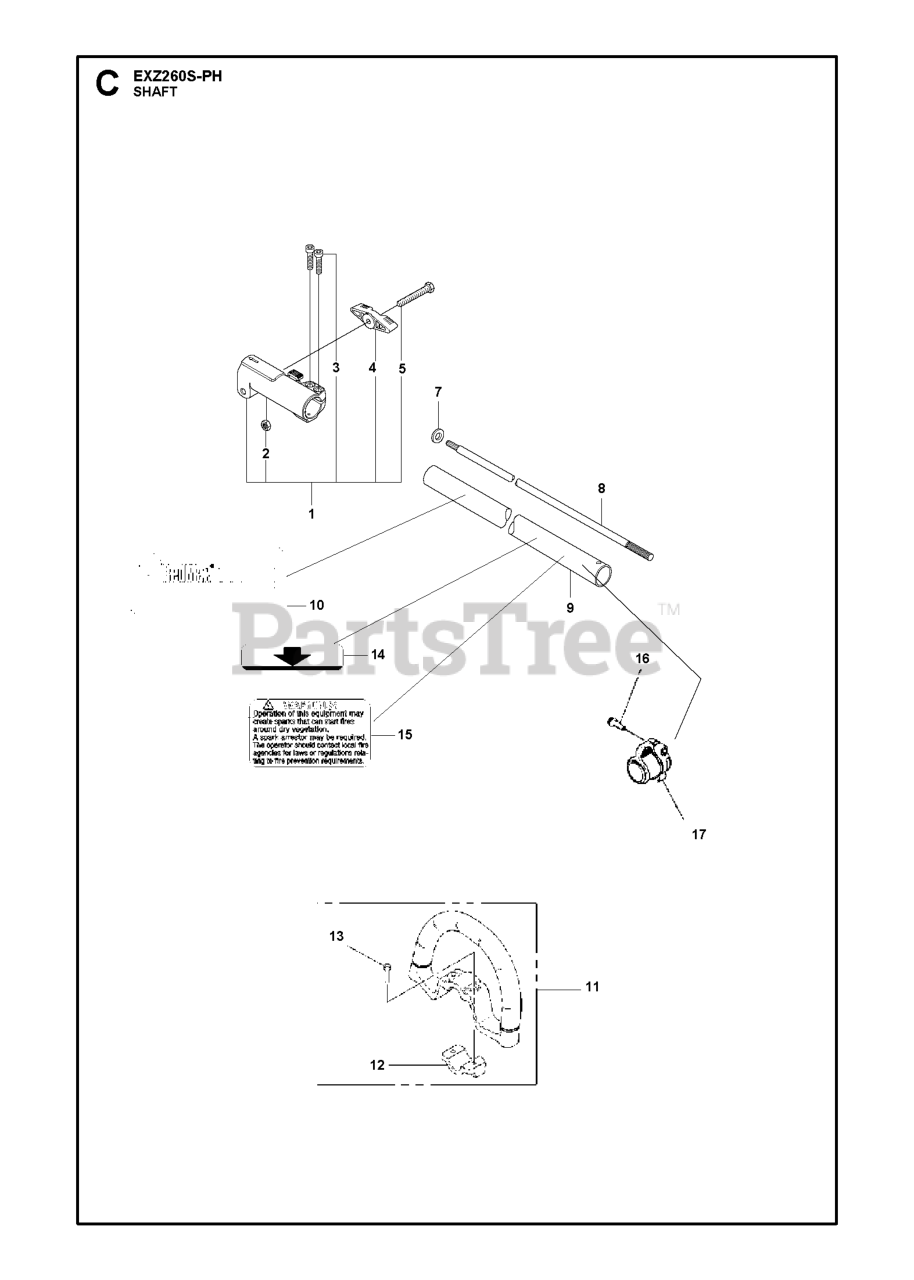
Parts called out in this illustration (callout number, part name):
1	SLEEVE CLAMPING ASSY
4	KNOB CLAMPING SLEEVE
5	SCREW
8	DRIVE SHAFT
9	TUBE COMP UPPER 525LDX
11	HANDLE LOOP
12	CLAMP HANDLE
15	DECAL SPARK ARRESTOR WARNING
17	HANGER COMP
